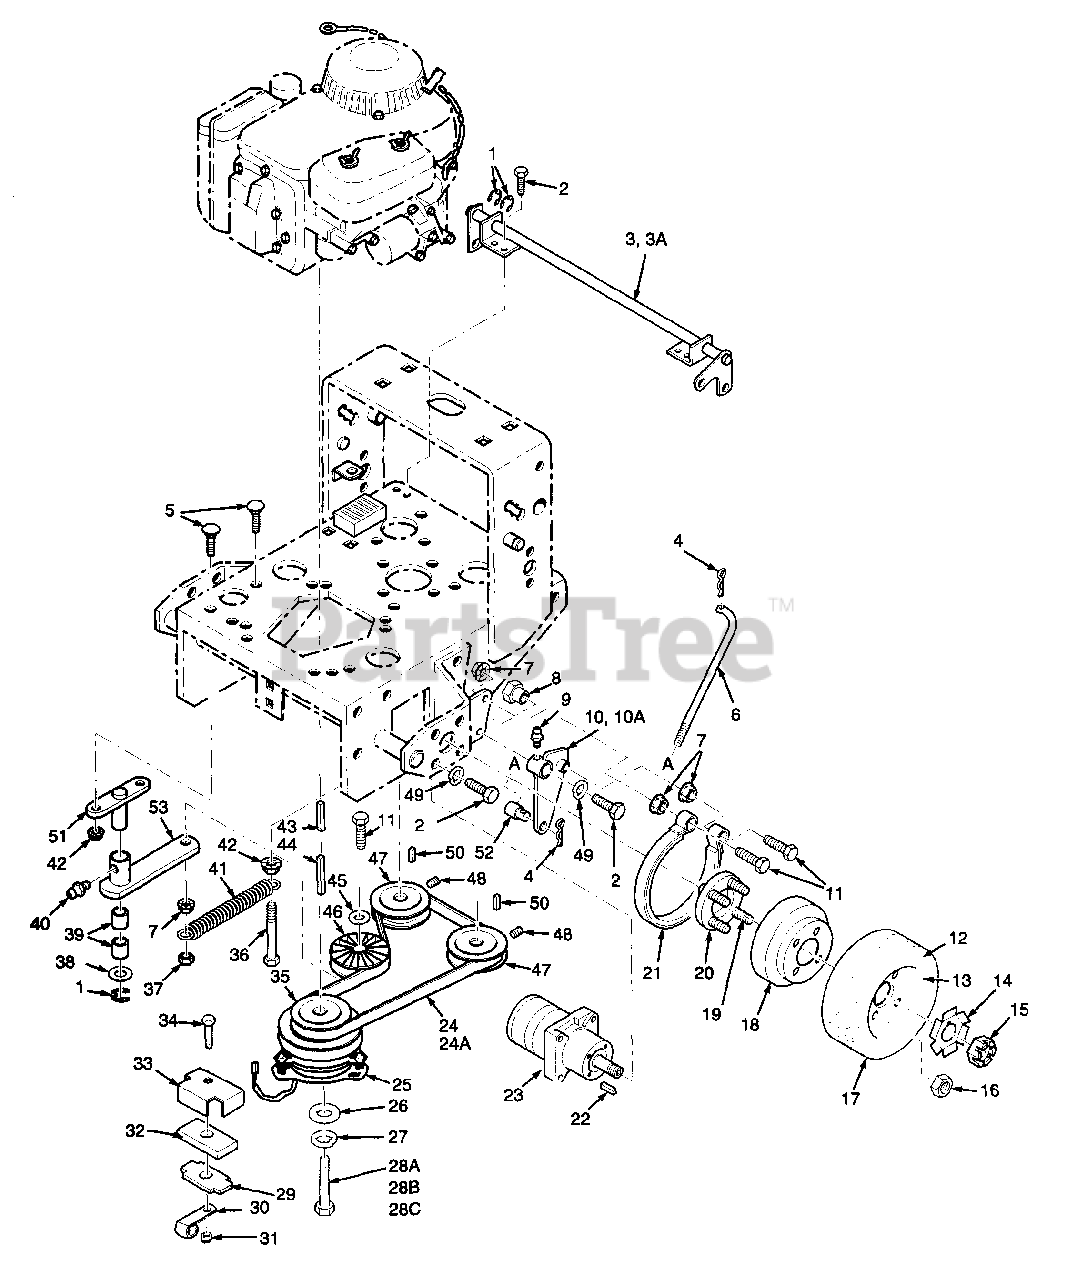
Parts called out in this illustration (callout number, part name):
1	Retaining Ring, 3/4 Ext. "E"
2	Bolt, 3/8-16 x 1" Hex Head
3	Brake Shaft Assy. Wlmt. Small
3A	Brake Shaft Assy. Wlmt. Large
4	Hair Pin Cotter, .094 x 1.62
5	Carriage Bolt, 5/16-18 x .75"
6	Rod, Brake Lower
7	Nut, 3/8-16 Serr. Flange
8	Bushing, Brake
9	Grease Fitting
10	Brake Actuator Wlmt., LH
10A	Brake Actuator Wlmt., RH
11	Bolt, 3/8-16 x 2-1/4"
12	Tire, 16 x 6.50, 4 ply
13	Rim Assy
14	Lock Washer, Wheel Motor
15	Hex Castle Nut, 3/4-28 UNEF
16	Nut, Lug
17	Wheel Assy.
18	Brake Drum
19	1/2-20 Serrated Bolt
20	Hub, Wheel
21	Brake Band, 7.5"
22	Key, 3/16 X .75 Woodruff
23	Wheel Motor
24	Belt, Pump Drive (Sm Frame)
24A	Belt, Pump Drive (Lg Frame)
25	Electric Clutch
26	Flat Washer .469 x 1.75 x .25
27	Lock Washer, 7/16
28B	Hex Head Bolt, 7/16-20 x 2.00"
29	Plate, Backing
31	Nut, 5/16-18 Elastic Stop
32	Rubber Pad, Clutch Stop
33	Retainer, Clutch Stop
34	Hex Head Bolt, 5/16-18 x 1.75"
35	Pulley, Pump Drive Engine
36	Hex Head Bolt, 5/16-18 x 2.75"
37	Nut, 3/8-16 Center Lock
38	Washer, 3/4-.766 x 1.2 x .06
38	Washer, 3/4-.766 x 1.2 x .035
39	Bushing, 3/4 Sintered
40	Grease Fitting, Str. 1/4-28
41	Spring, Pump Belt Idler
42	Nut, 5/16-18 Serr. Flange
43	Key, 1/4 x 1/4 x 2.75" Clutch Mtg.
44	Key, 1/4 x 1/4 x 1.25" Pulley Mtg.
45	Flat Washer, 3/8
46	Pulley, Idler Pump Drive
47	Pulley, Pump Shaft
48	Setscrew, 5/16-18 x 3/8"
49	Lockwasher, 3/8
50	Key, 5.0 x 5.0 x 25mm
51	Pivot, Idler Arm
52	Swivel Joint
53	Arm, Idler
